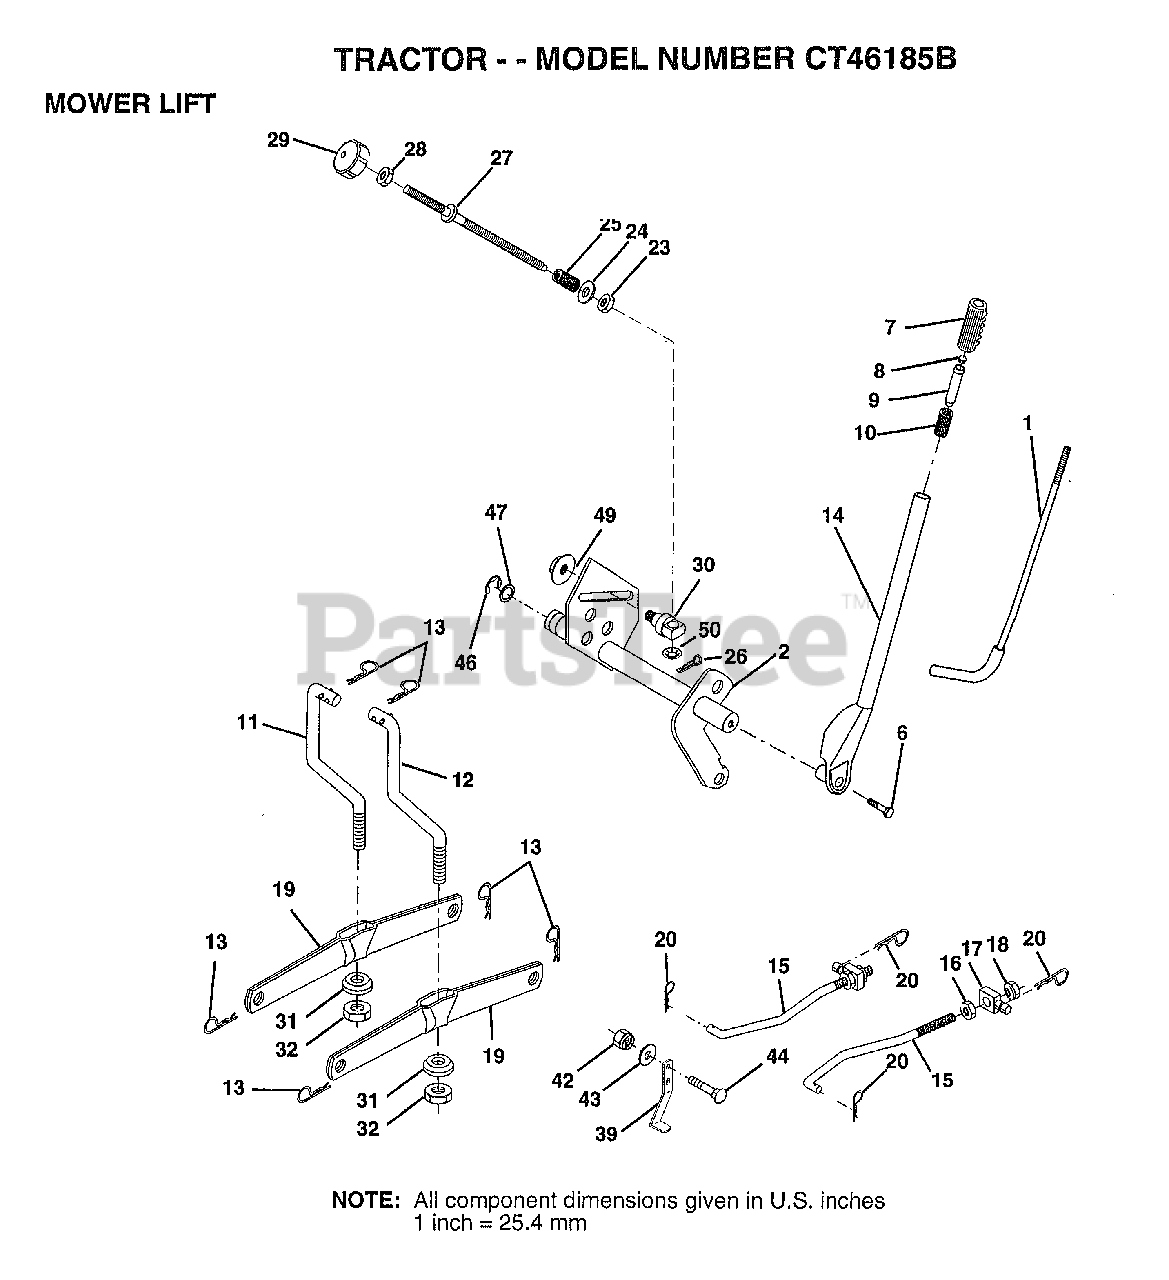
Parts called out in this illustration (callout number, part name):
1	LEVER ROD LT
2	LEVER ASSY LIFT.RH.
6	"BOLT,HEX"
7	GRIP
10	SPRING T
11	LINK.LIFT.LH.GTV
12	LINK.LIFT.RH.GTV.
14	LEVER.ASM.LIFT.RH
15	LINK.FRONT
16	NUT
17	TRUNION
18	NUT LTV
19	ARM SUSP REAR
20	RETAINER SPRING
23	NUT T
24	WASHER
25	SPRING.COMP.INF.H
27	ROD.ADJ.LIFT
28	NUT
29	KNOB INF 3/8-16
30	TRUNNION
31	BEARING PVT LH
32	NUT.CROWNLOCK.3/8
39	STOP.OVER.CENTER
43	WASHER GT
44	BOLT
46	E-RING
47	WASHER
49	NUT.HXFLG.LOCK.
